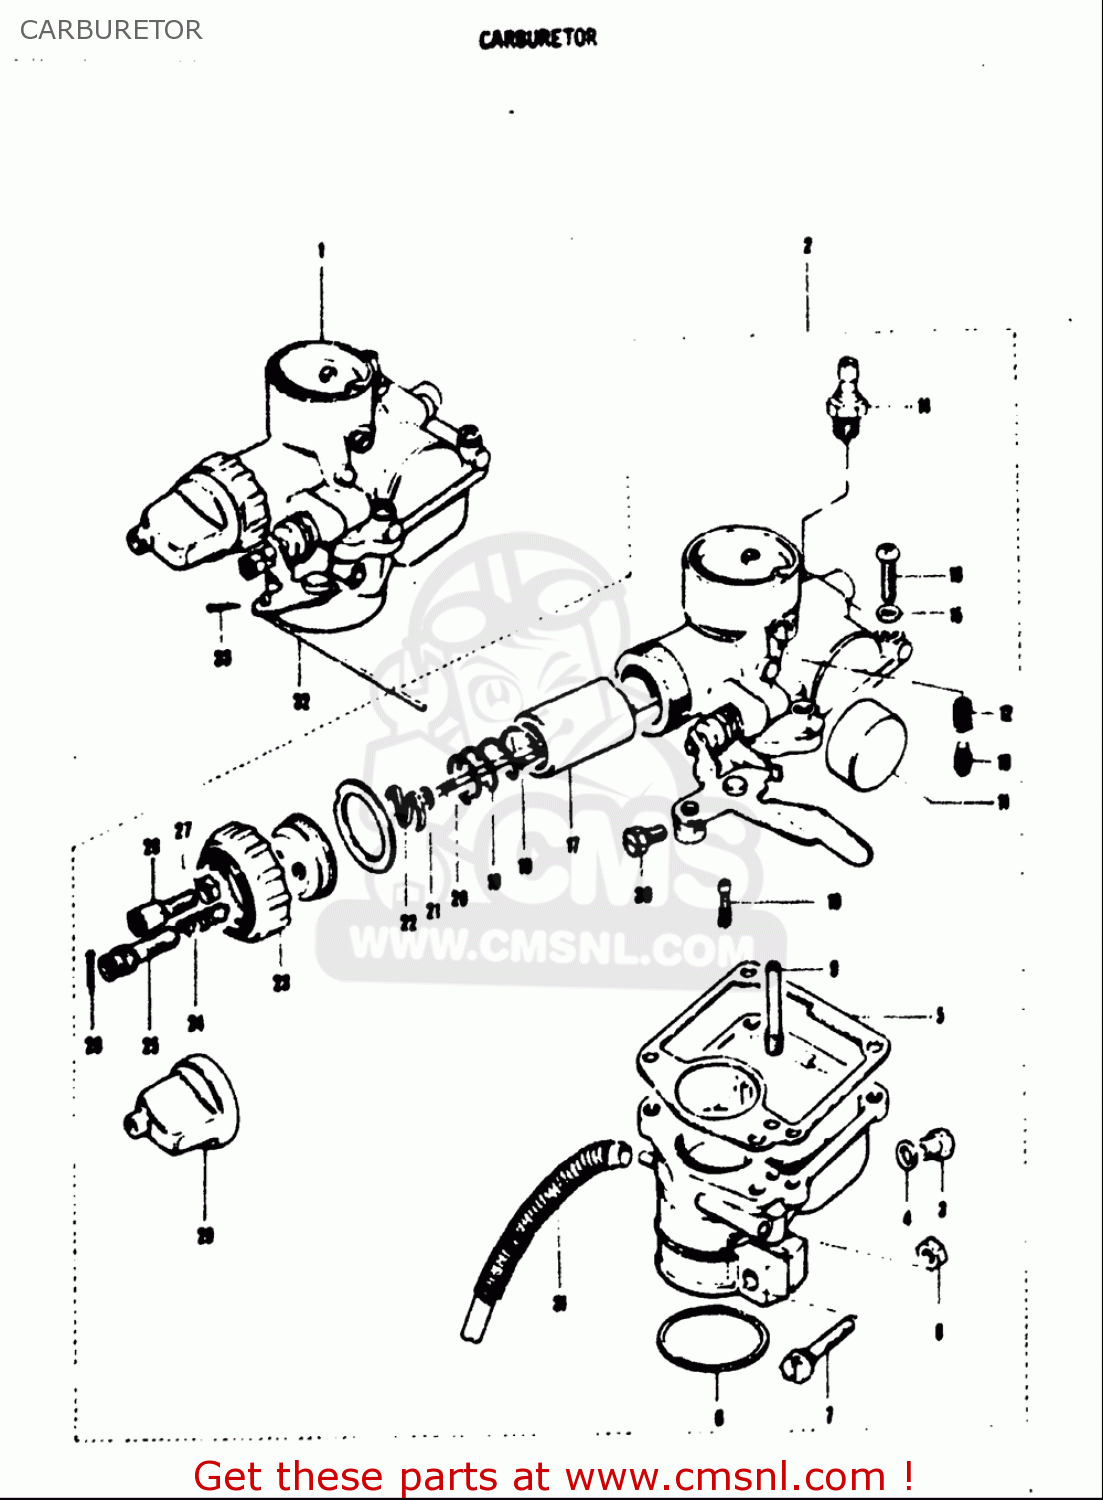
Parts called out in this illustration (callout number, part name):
4	GASKET,DRAIN,PLUG (NAS)
8	NUT
12	SPRING
13	SCREW,PILOT AIR
15	WASHER,LOCK
16	SCREW 4X16
18	SPRING,THROTTLE VALVE
21	CLIP,NEEDLE
24	SPRING,THROTTLE SCREW
25	SCREW,THROTTLE VALVE ADJUST
27	NUT
28	ADJUSTER,CABLE
30	BOLT, STARTER ROD
